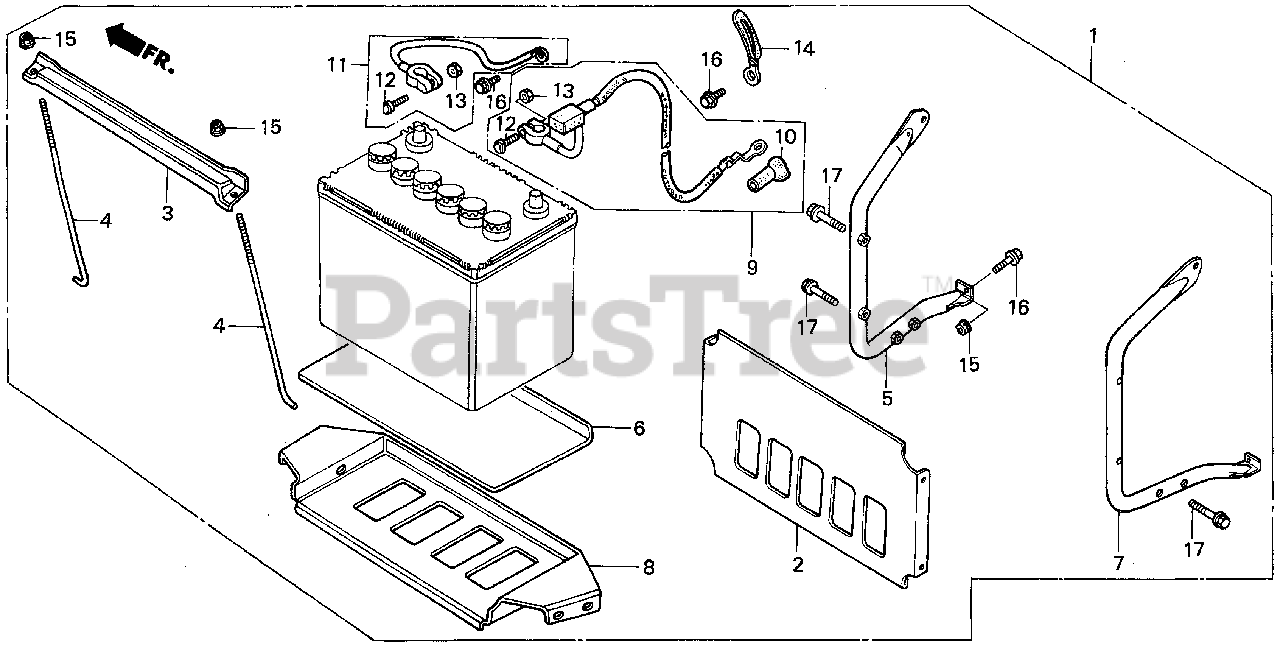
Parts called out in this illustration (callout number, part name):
1	BATTERY TRAY KIT
2	PLATE, BATTERY GUARD
3	PLATE, BATTERY SETTING
4	BOLT, BATTERY SETTING (220MM)
5	GUARD, FR. BATTERY
6	PLATE, BATTERY Use from Frame SN 1127014.
7	GUARD, RR. BATTERY (NOT AVAILABLE)
8	BASE, BATTERY TRAY
9	CABLE ASSY., STARTING
10	COVER, STARTER MOTOR TERMINAL
11	CABLE ASSY., GROUND
12	BOLT, BATTERY TERMINAL (SUMITOMO)
12	BOLT, BATTERY TERMINAL
13	NUT, BATTERY TERMINAL (SUMITOMO)
14	CLIP, HEAD
15	NUT, FLANGE (6MM)
16	BOLT, FLANGE (6X12) Use up to Engine SN 1543277.
17	BOLT, FLANGE (6X28)
NI	BATTERY (GR.51) (NOT AVAILABLE) (MSDS)
